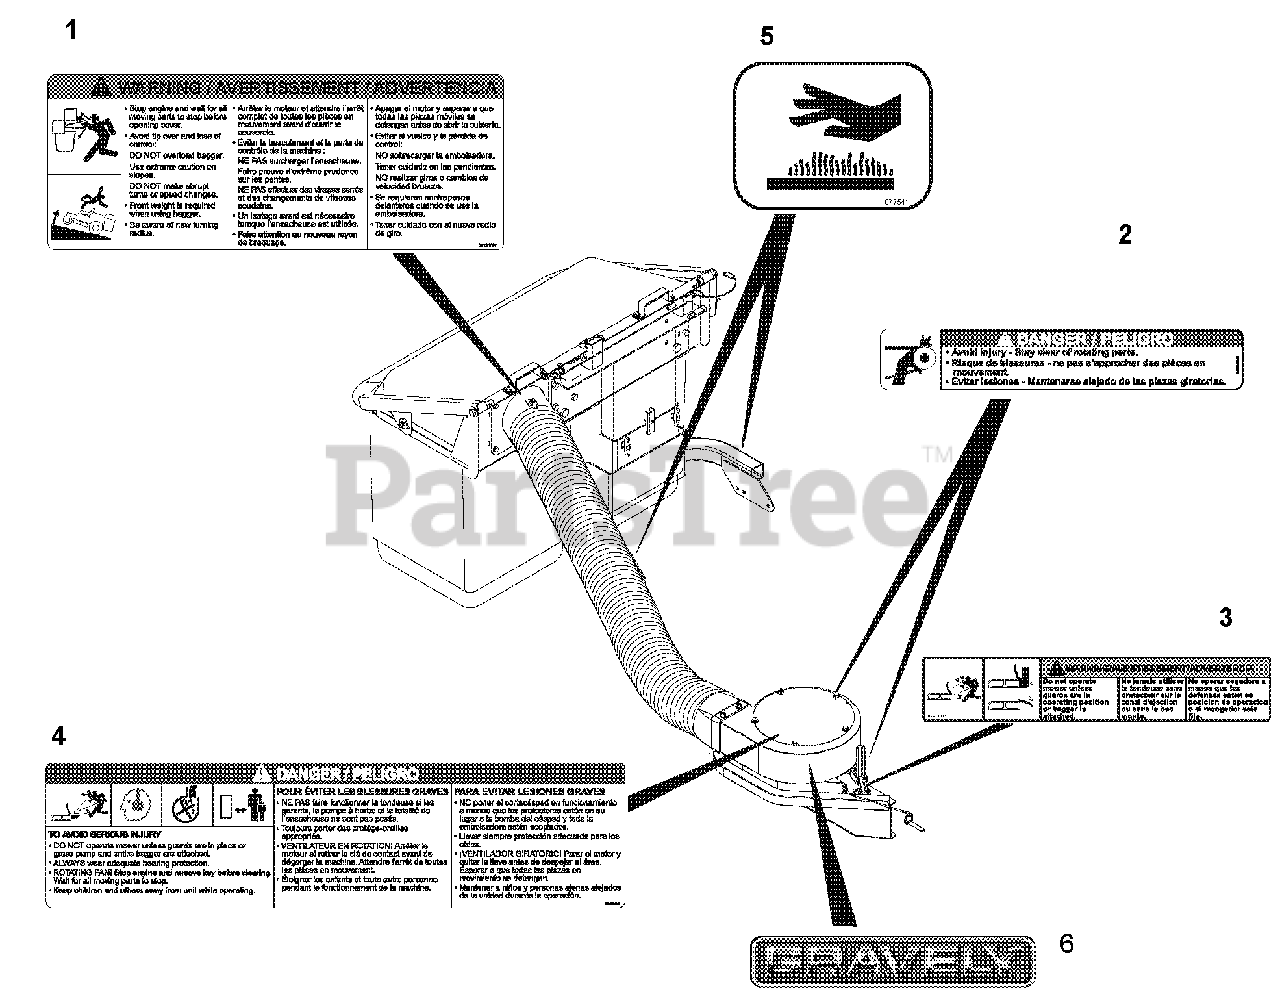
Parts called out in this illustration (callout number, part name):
1	Bagger Cover Decal
2	Decal, Danger
3	Decal, Warning
4	Decal, Caution Grass Pump
5	Decal, Hot Surface
6	Decal, Gravely
